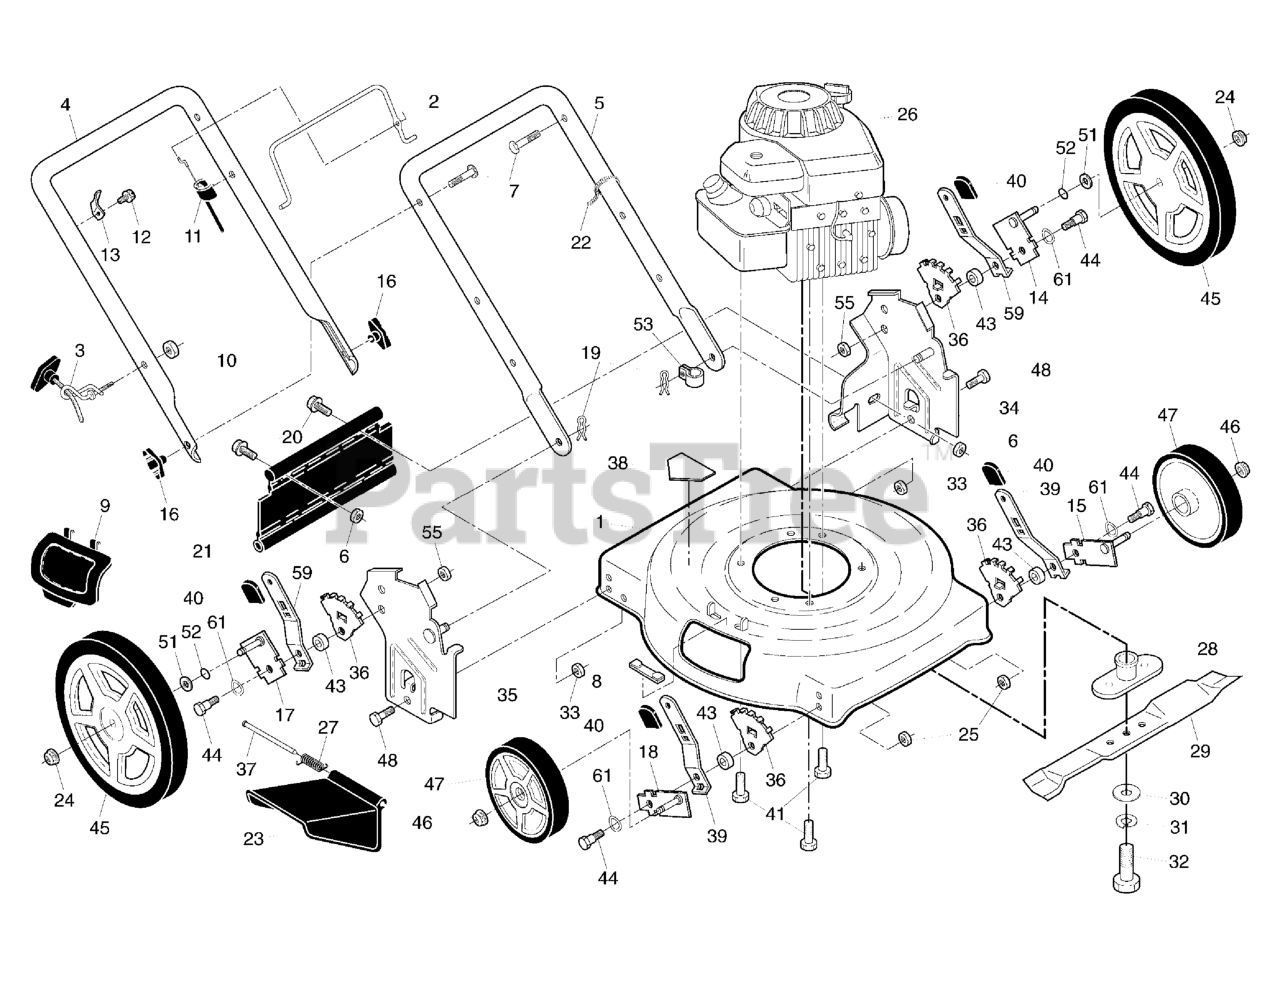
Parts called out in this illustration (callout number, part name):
1	** KIT, Housing (Includes Key Number 38)
2	CONTROL BAR
3	GUIDE, Rope
4	HANDLE, Upper
5	HANDLE, Lower
6	LOCKNUT, Hex, 1/4-20
7	BOLT, Handle, 5/16-18
8	CLIP, Closeout
9	MULCHER PLATE
10	LOCKNUT, Hex, 1/4-20
11	CABLE, Engine Zone Control
12	SCREW, Hex Head, Threaded, Rolled, #10-16 x 5/8
13	BRACKET, Upstop
14	AXLE ARM ASSEMBLY, Rear, LH
15	AXLE ARM ASSEMBLY, Front, LH
16	KNOB, Handle
17	AXLE ARM ASSEMBLY, Rear, RH
18	AXLE ARM ASSEMBLY, Front, RH
19	Hairpin Cotter
20	CAPSCREW, Hex Head, 1/4-20
21	DEFLECTOR, Rear
22	Wire Tie
23	GUARD, Discharge
24	** NUT, Flangelock, 3/8-16
25	NUT, Hex, Flangelock 5/16-18
26	* ENGINE, Briggs & Stratton
27	SPRING, Torsion
28	ADAPTER, Blade
29	BLADE, 22"
30	WASHER, Hardened
31	LOCKWASHER, Helical, 3/8
32	SCREW, Hex Head, 3/8-24 x 1-3/8, G8
33	NUT, Hex, Flangelock 5/16-18
34	SUPPORT, Wheel Bracket, LH
35	SUPPORT, Wheel Bracket, RH
36	ADJUSTER, Wheel Bracket
37	HINGE ROD
38	DECAL, Danger
39	SPRING, Selector
40	KNOB, Selector
41	SCREW, Hex Head, Threaded, 3/8-16 x 1
43	SPACER
44	BOLT, Shoulder, 5/16-18 x .33
45	WHEEL & TIRE ASSEMBLY, Rear
46	NUT, Hex, Flangelock 3/8-16
47	WHEEL & TIRE ASSEMBLY, Front
48	BOLT, Hex Head, 5/16-18
51	WASHER, Flat, 3/8
52	O-RING
53	CLIP, Cable
55	Nut, Hex
59	Selector Spring, Rear
61	WASHER, Curved, Cylindrical
